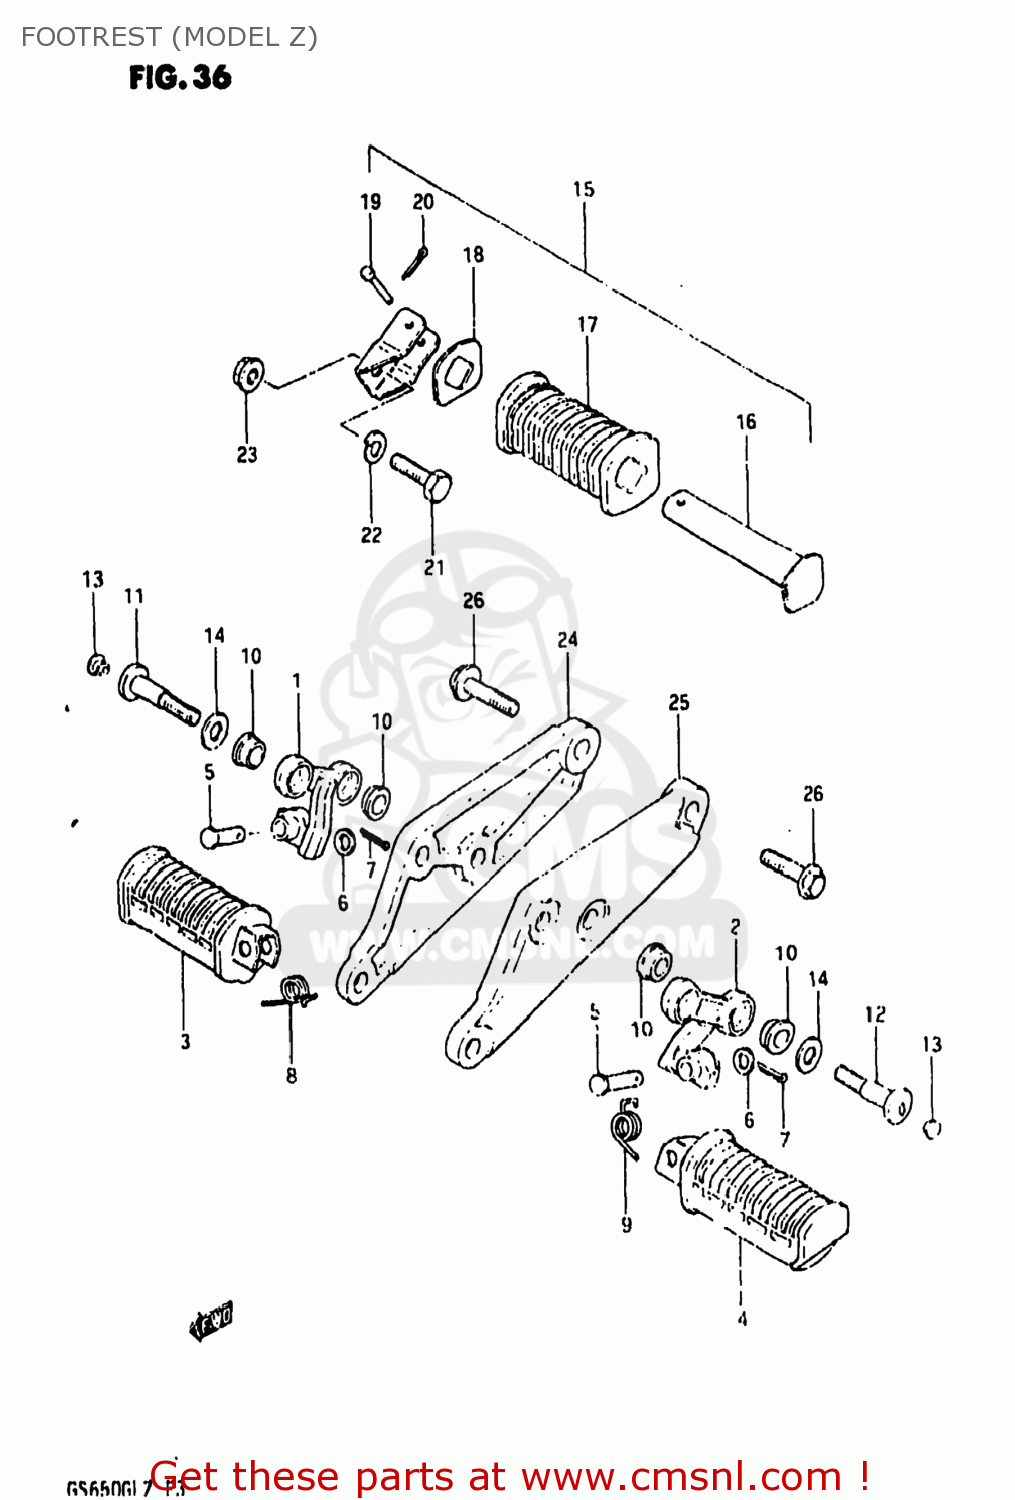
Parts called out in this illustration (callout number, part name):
1	BAR,FRONT FOOTREST,RIGHT
2	BAR,FRONT FOOTREST,LEFT
3	RUBBER,FOOTREST
4	FOOTREST
5	PIN
6	WASHER
7	PIN
8	SPRING
9	SPRING
10	BUSH
11	BOLT
12	BOLT
13	CAP
14	WASHER(10.5X28X2.3)
15	FOOTREST ASSY,PILLION,R
16	BAR,REAR FOOTREST,LEFT
17	RUBBER,PILLION FOOTREST
18	WASHER,FOOTREST RUBBER
19	PIN
20	PIN
21	BOLT,M10X1.25X
22	LOCK WASHER
23	NUT
24	BRACKET,MUFFLER,RIGHT
25	BRACKET,MUFFLER,LEFT
26	BOLT
